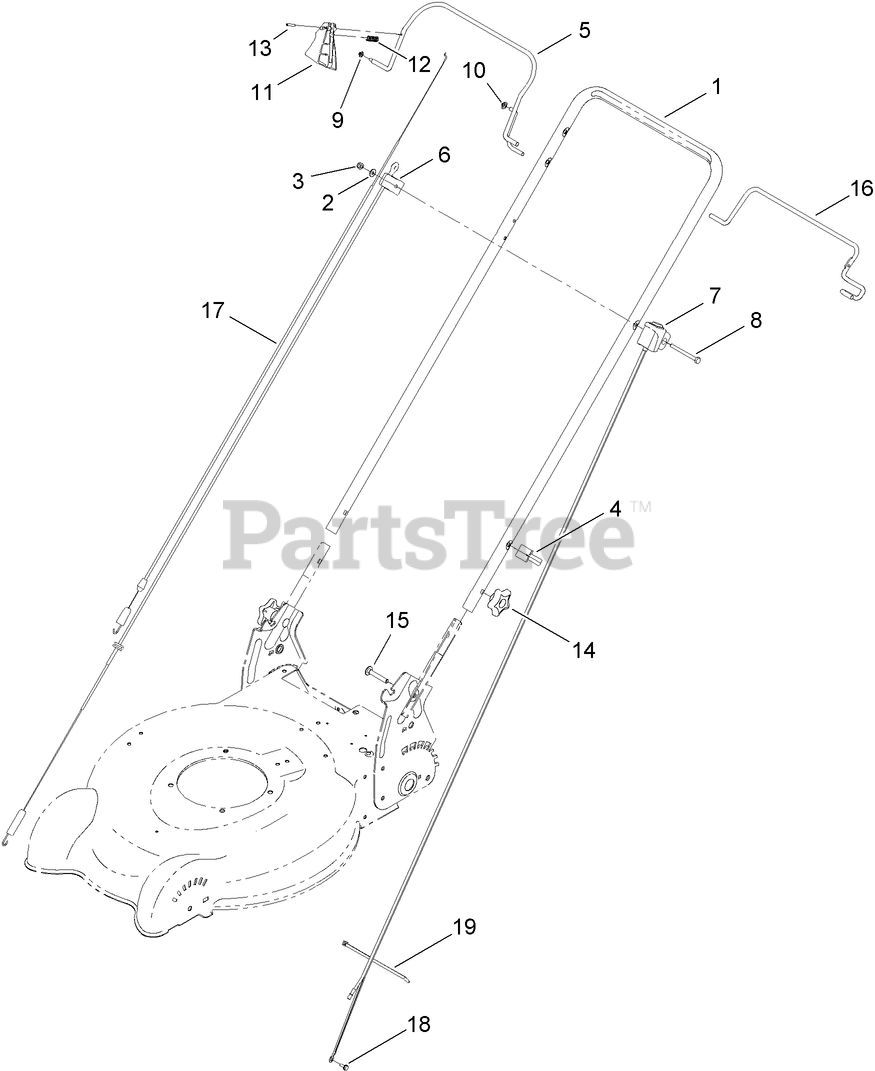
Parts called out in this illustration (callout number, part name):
2	WASHER-FLAT
3	NUT-LOCK, NI
4	GUIDE-CABLE
6	CABLE-BRAKE
7	SWITCH HOUSING ASM
8	SCREW-HH
10	NUT-SPEED
11	STOP-BAIL
12	SPRING-COMPRESSION
13	PIN-ROLL
14	KNOB-HANDLE
15	BOLT-CARR
16	BAIL-TRACTION, 2-BAIL FLAT
17	CABLE-TRACTION
18	SCREW-TAPTITE
19	TIE-CABLE
